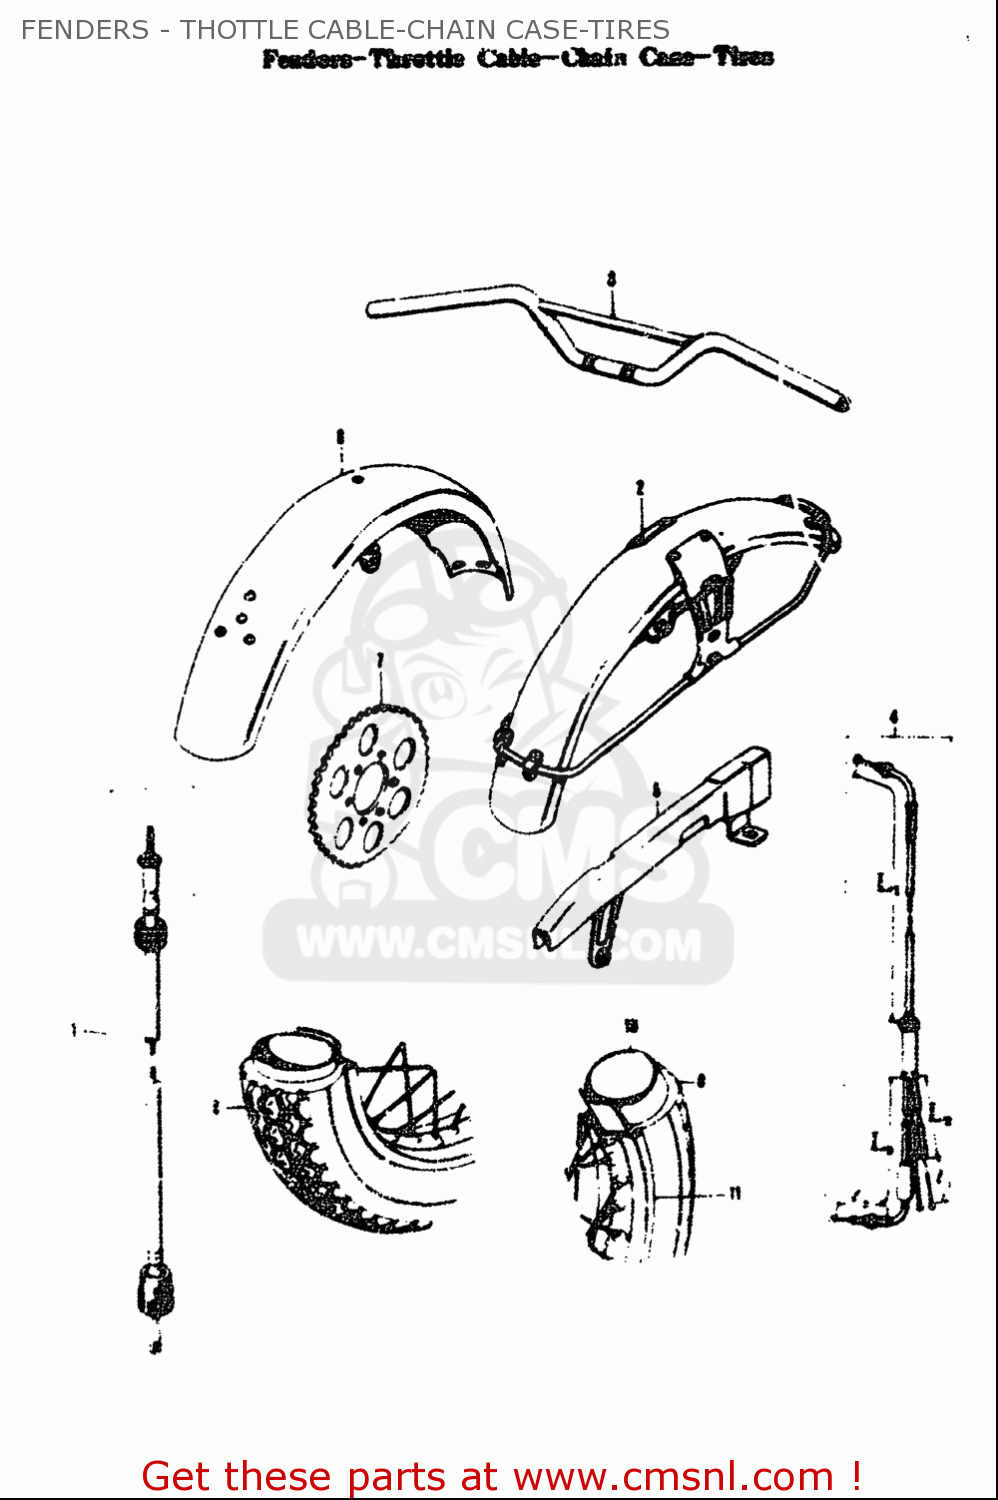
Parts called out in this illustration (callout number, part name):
1	CABLE ASSY,SPEEDOMETER
10	TUBE ASSY,INNER
11	RIM,RR WHEEL
